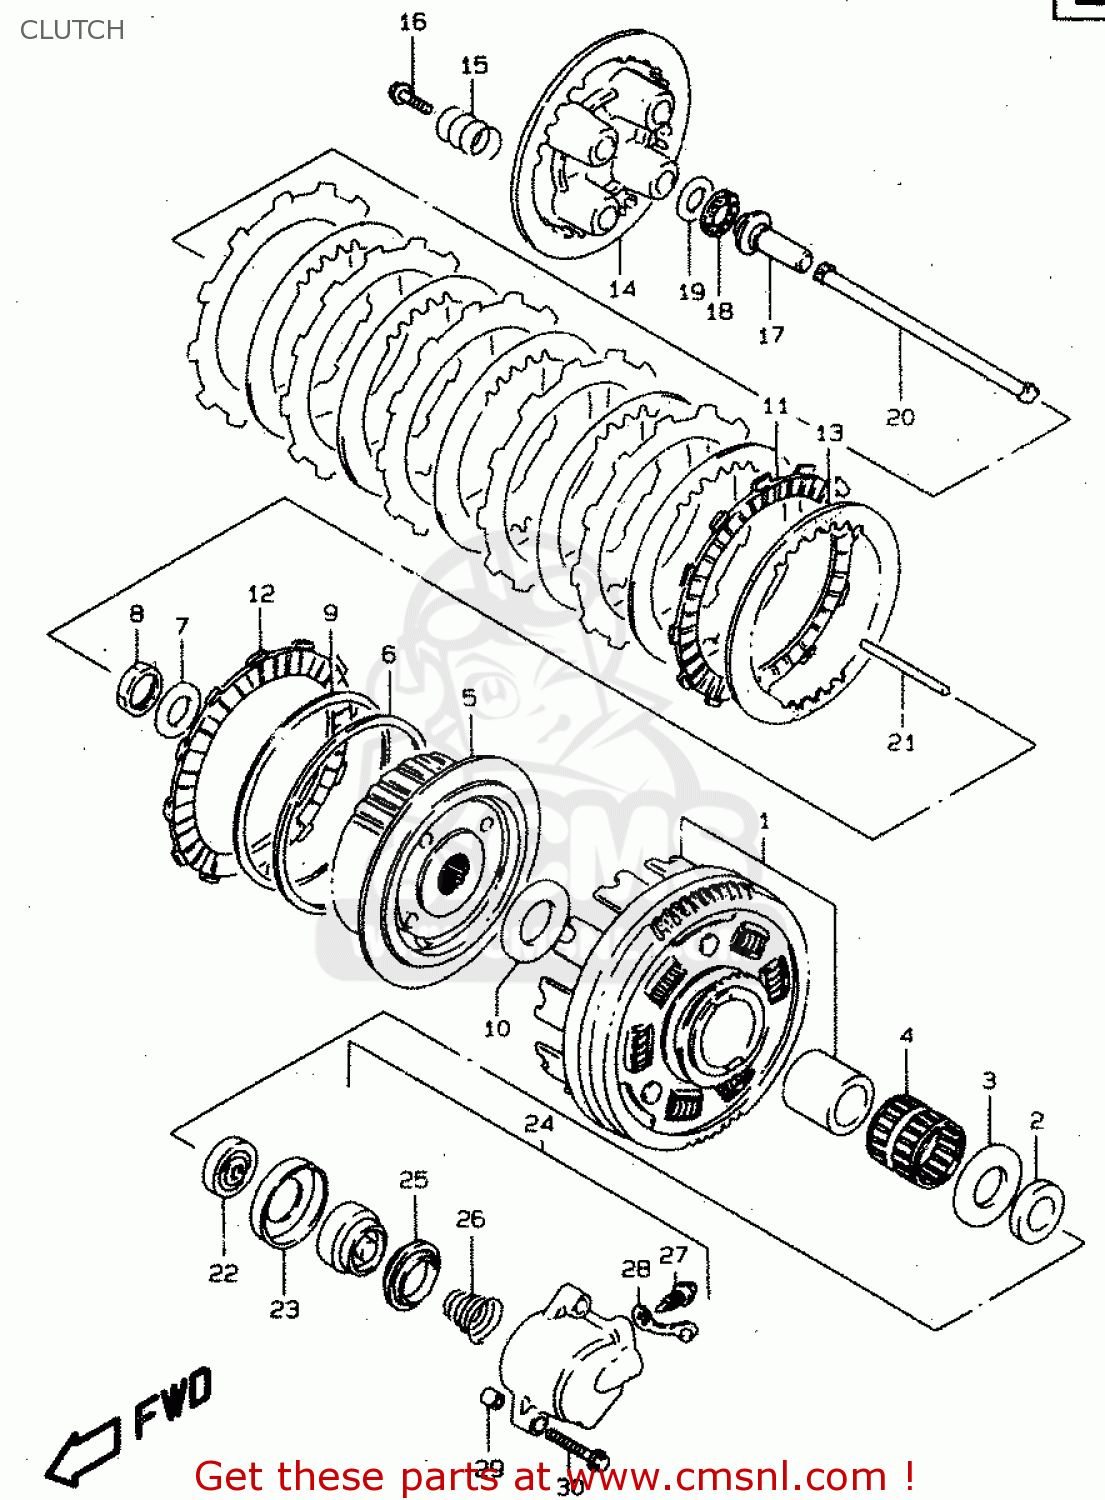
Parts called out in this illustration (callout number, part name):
1	GEAR ASSY,PRIMARY(NT:71)
2	SPACER(25X38X6.5)
3	WASHER(25X50X2.5)
4	BEARING(35X40X35.8)
5	HUB COMP,CLUTCH SLEEVE
6	SEAT,WAVE WASHER(T:1.4)
7	WASHER
8	NUT
9	WASHER
10	WASHER(25X50X2.5)
11	PLATE,CLUTCH DRIVE (NAS)
12	PLATE,CLUTCH DRIVE(T:3.5) (NAS)
13	PLATE,CLUTCH DRIVEN(T:1.6) (NAS)
14	DISC,CLUTCH PRESSURE
15	SPRING
16	BOLT(6X16)
17	PIECE,CLUTCH PUSH
18	BEARING(15X28X2)
19	WASHER(15.5X28X1)
20	ROD,CLUTCH
21	ROD,CLUTCH PUSH,L
22	SEAL,OIL(6X34X11)
23	RETAINER,CL PUSH ROD OIL SEAL
24	CYLINDER,CLUTCH RELEASE
25	CUP,CLUTCH CYLINDER
26	SPRING,CLUTCH CYLINDER
27	BLEEDER
28	CAP,BLEEDER
29	PIN
30	BOLT
